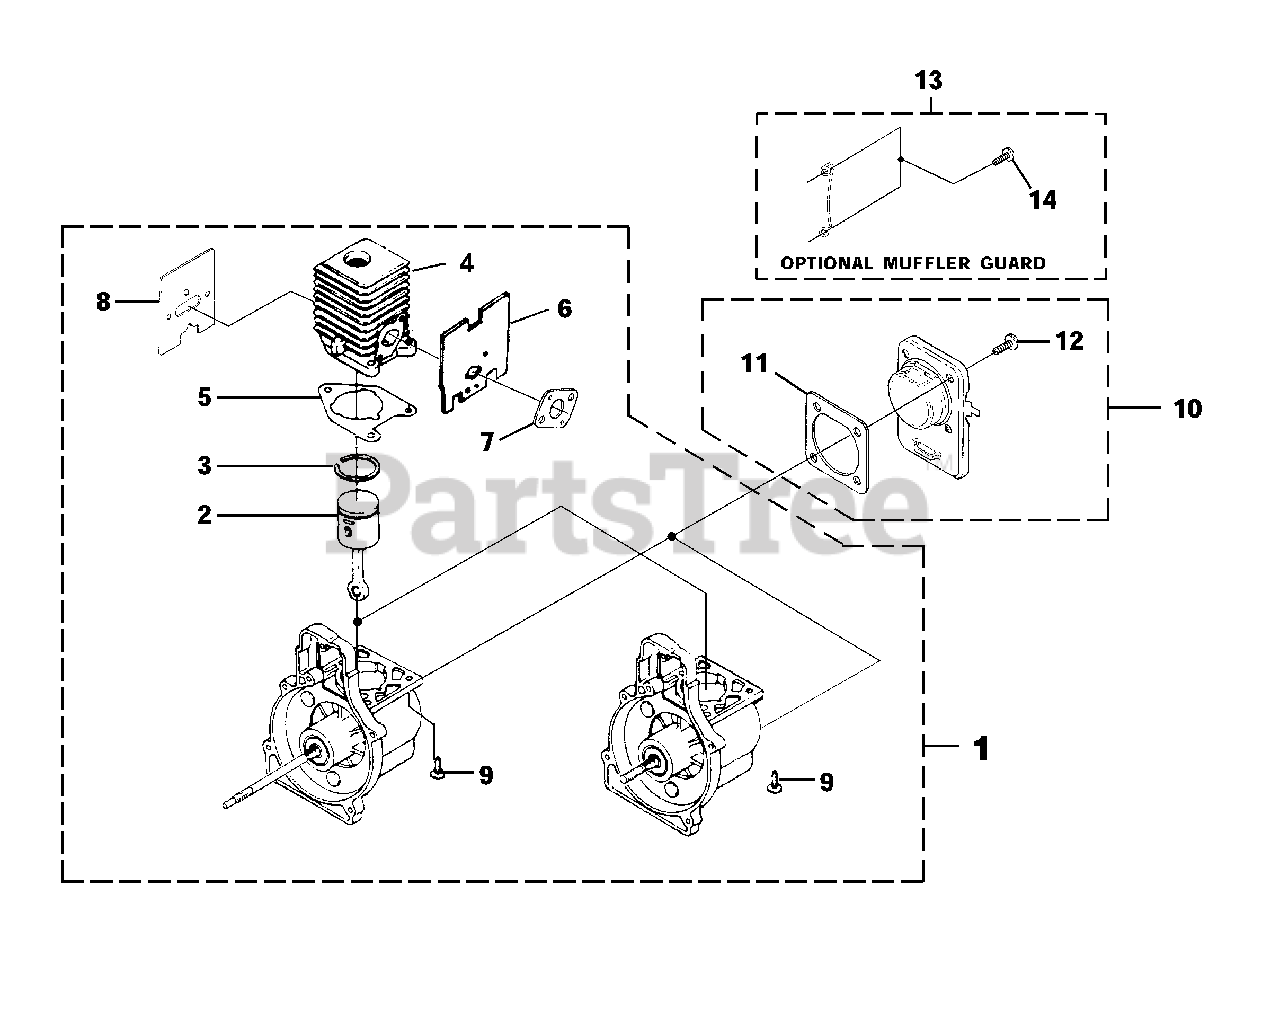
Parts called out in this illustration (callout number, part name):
1	SHORT BLOCK (Non-Clutch)
2	PISTON & ROD ASSY.
3	RING-Piston
4	CYLINDER ASSY.
5	GASKET-Cylinder
6	GASKET-Heat Dam
7	GASKET-Carburetor
8	GASKET-Muffler
9	SCREW-Sems (12-24 X 3/4")
10	CRANKCASE COVER ASSEMBLY
11	GASKET-Crankcase Cover
12	SCREW-Sems (10-24 X 1/2")
13	MUFFLER GUARD
14	SCREW-Plastite (10-14 X 1/2")
